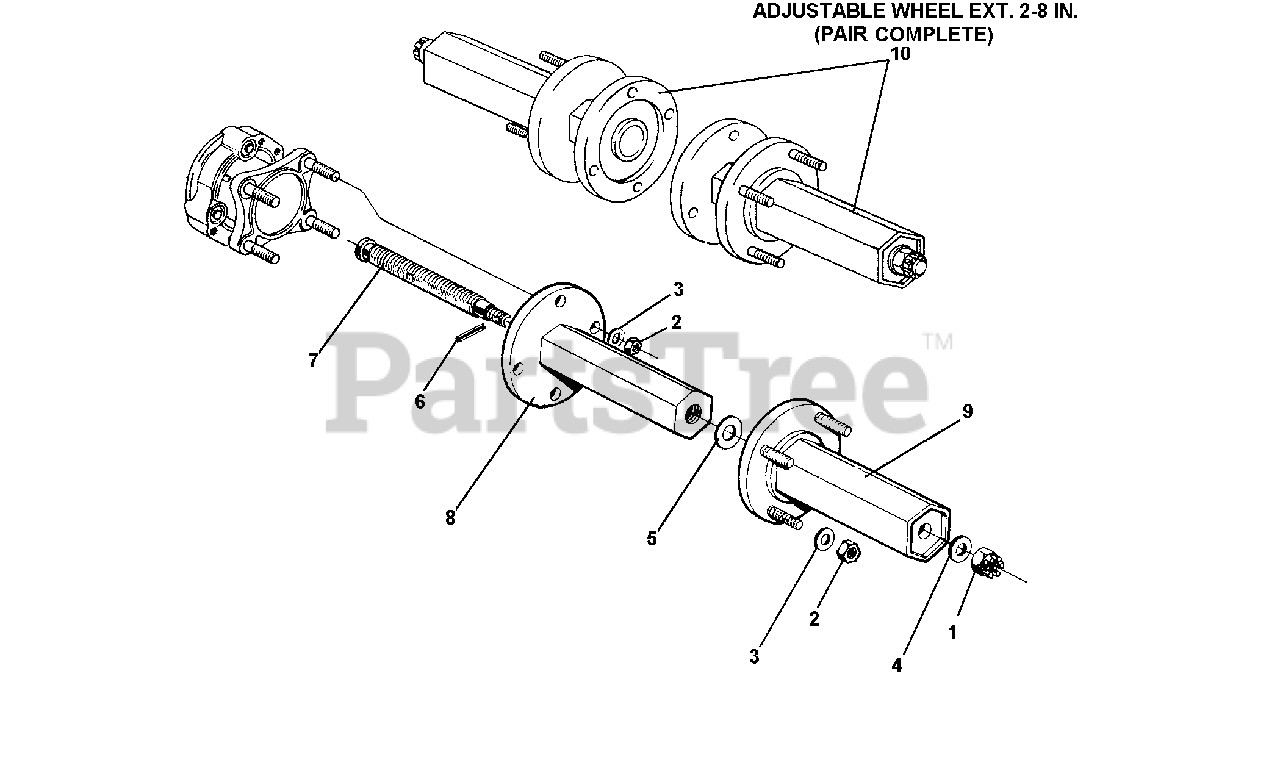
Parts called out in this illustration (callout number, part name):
1	NUT, HEX INT M12 UNI 5593 6S
3	WASHER, LOCK 10.5
4	WASHER, LOCK 13
5	WASHER, LOCK 17
6	PIN, LOCKING SW 3 X 18 SPIRAL
7	SCREW ADJUSTMENT
8	FLANGE CONNECTION
9	FLANGE ADJUSTABLE
10	ADJUST. WHEEL EXT. COMPLETE (PR)
